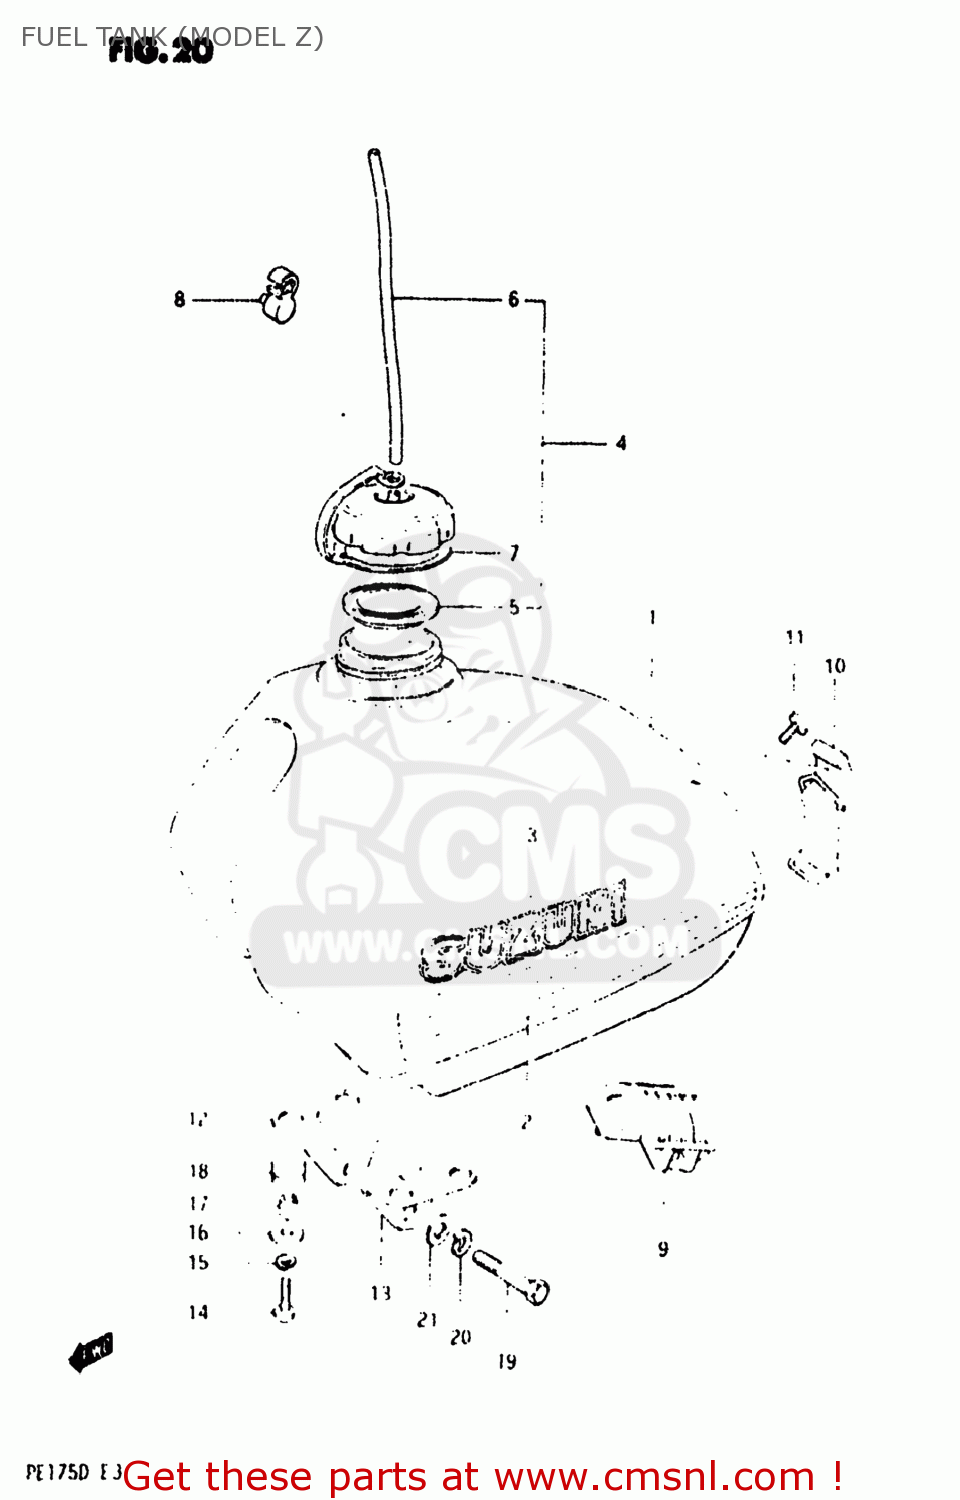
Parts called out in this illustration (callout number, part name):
1	TANK ASSEMBLY,FUEL
2	TAPE SET,FUEL TANK
3	EMBLEM
4	CAP,FUEL TANK
5	GASKET,FUEL TANK CAP (NAS)
6	HOSE
7	BAND,FUEL TANK CAP
8	CLAMP,BREATHER HOSE
9	CUSHION,FUEL TANK
10	BAND,FUEL TANK,REAR
11	SCREW(6X18)
12	BRACKET,FUEL TANK,LOWER
13	BRACKET,FUEL TANK
14	SCREW
15	LOCK WASHER
16	WASHER (6.5X24X1.6)
17	SPACER(6.8X12X11)
18	CUSHION
19	HEXAGON BOLT 8X80
20	LOCK WASHER
21	WASHER
